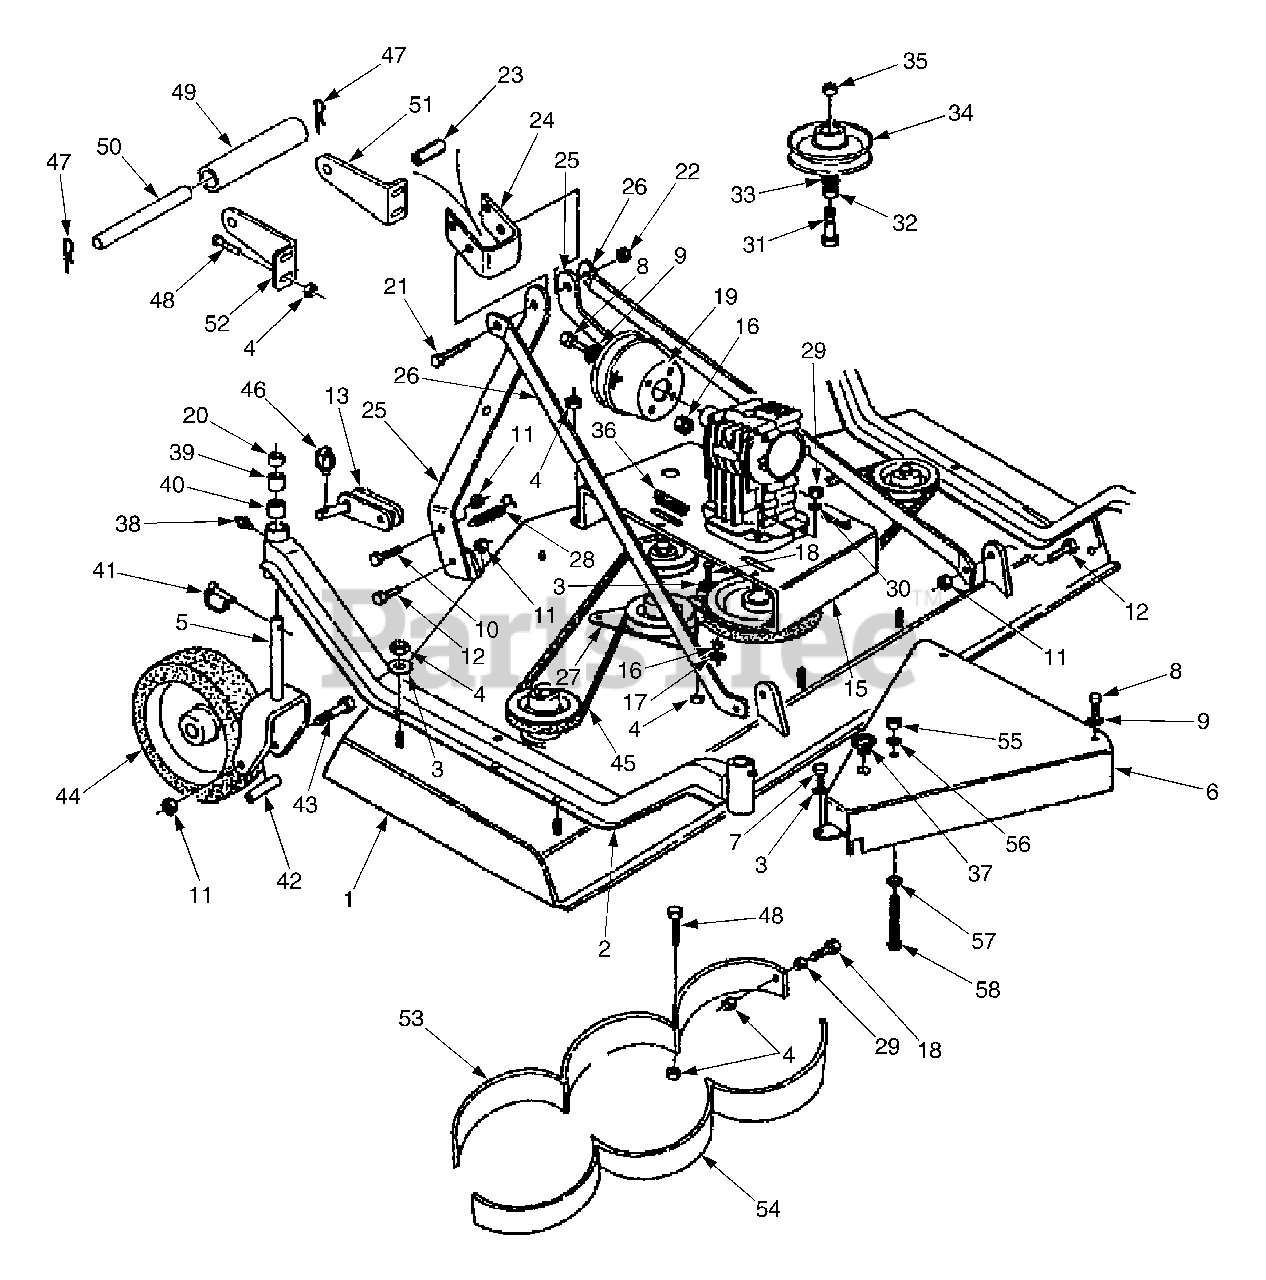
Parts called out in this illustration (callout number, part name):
1	Frame, 60" Rear Discharge
3	Flat Washer, M10
7	Bolt, 10 x 90
8	Bolt, 10 x 25
9	Flat Washer, M10
10	Bolt, 14 x 45
12	Bolt, 14 x 40
13	Hitch Block
15	Center Plate
17	Washer, M10
18	Bolt, 10 x 35
19	Shaft Protection (EC only)
20	Spacer, 1/4"
21	Bolt, 16 x 140
24	Upper Plate
25	Top Hitch Support
26	Top Hitch Arm
27	Support Belt Tensioner
29	Nut, M12
30	Lock Washer, M12
31	Bolt, 20 x 65
33	Flat Washer, M20
34	Pulley Belt Tensioner
37	Plastic Cap
38	Grease Fitting
39	Spacer, 1/2"
41	Cotter Pin, M6 x 45
43	Bolt, M14 x 140
45	Belt, 112-1/2
48	Bolt, 10 x 20
49	Front Roller
51	Right Roller Support
52	Left Roller Support
53	Front Mulching Kit Baffling
54	Rear Mulching Kit Baffling
56	Flat Washer, 10mm
57	Hex Nut, 10mm
58	Bolt, 10 x 110
